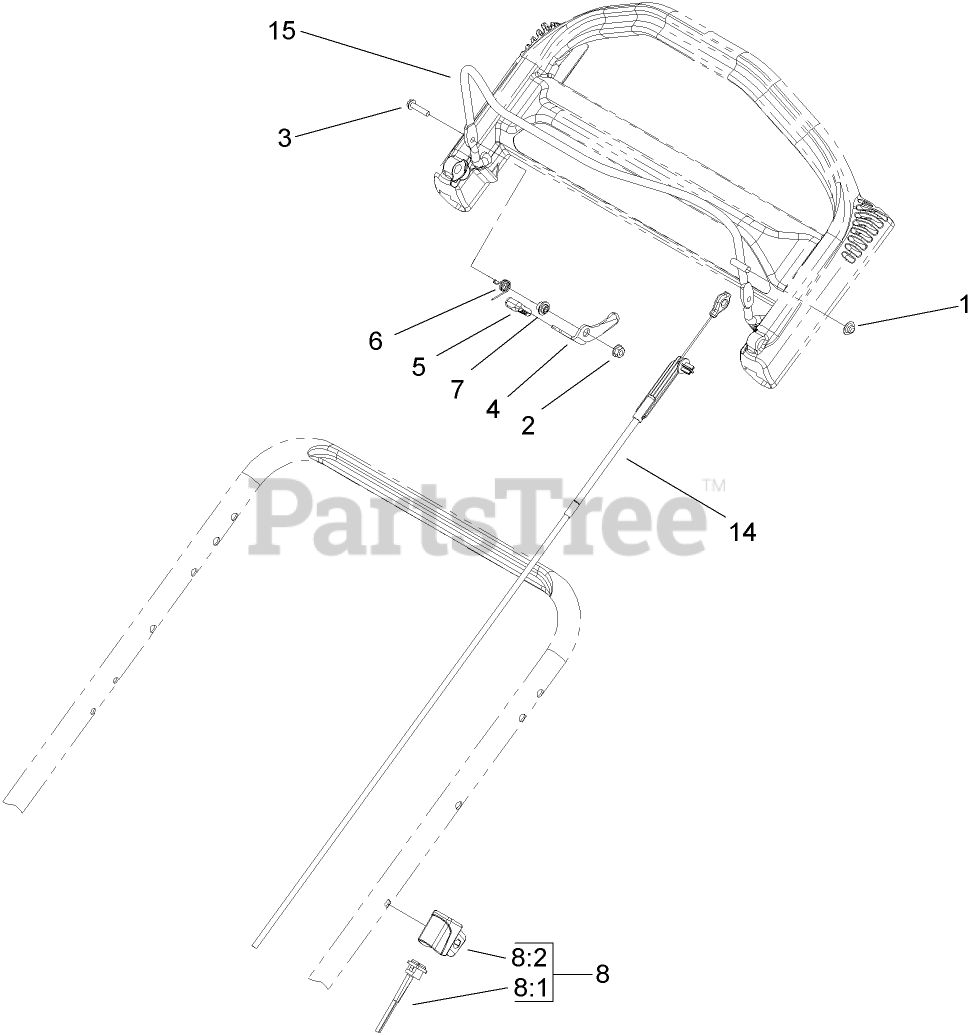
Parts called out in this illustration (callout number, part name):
1	NUT-SPEED
2	NUT-LOCK, FLANGE
3	SCREW-HWH
4	LEVER
6	SPRING-TORSION
7	SPACER
8	BBC SWITCH ASM
14	CABLE ASM
15	BAIL-BRAKE
